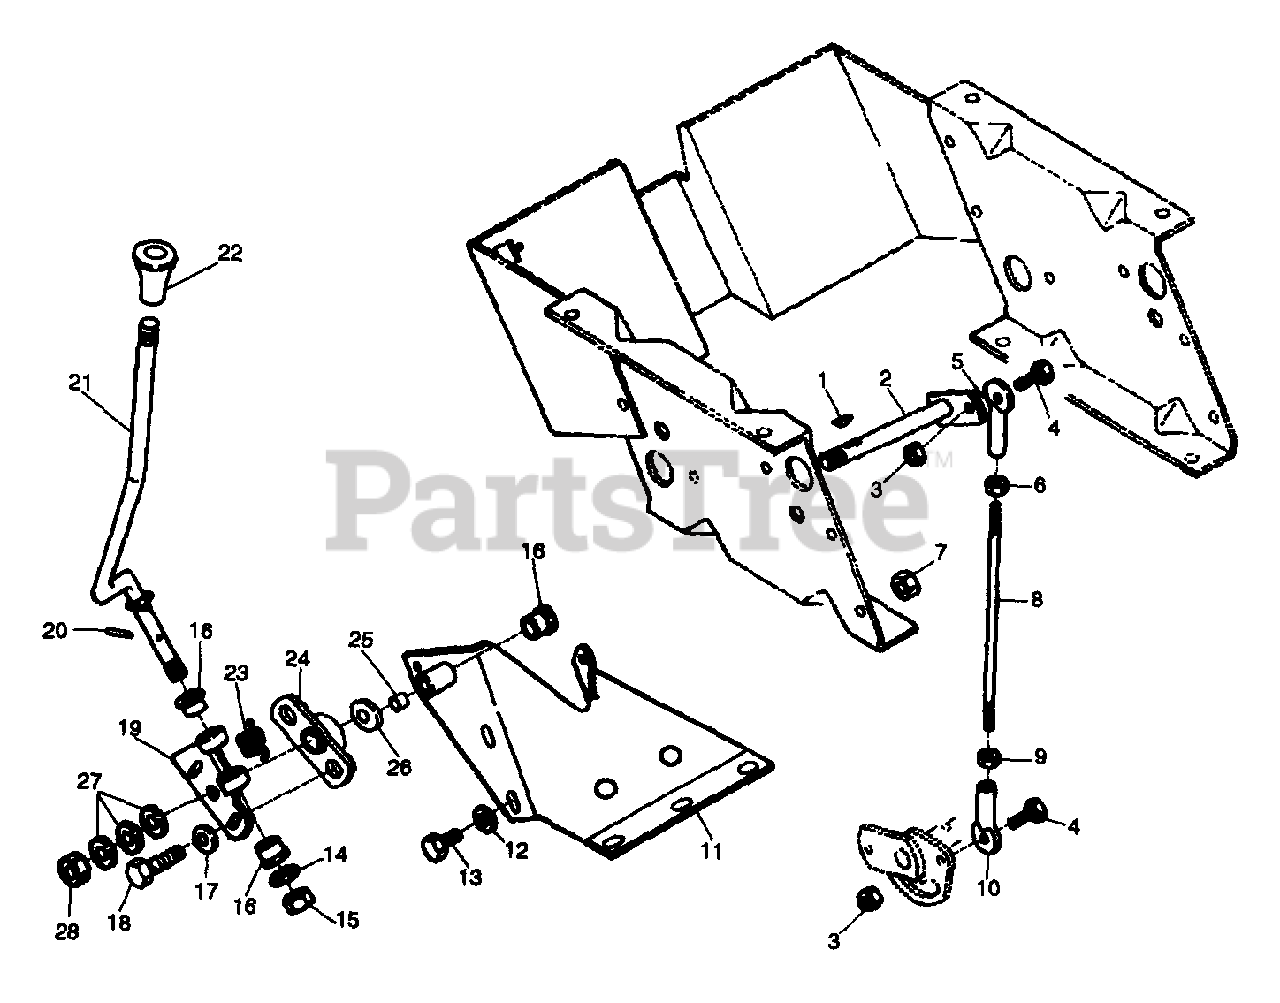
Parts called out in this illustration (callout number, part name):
1	KEY-WDRF .125X.500X.203 SAE 3
3	NUT-LK-CTR .250-20 PL
4	BLT-HEX .25-20X1.00 GR2
5	ROD END, 1/4 RH
6	NUT-HEX .250-28 YWZC
7	NUT-LK .312-18 GR A PL
8	SHIFT ROD
9	NUT-LH .250-28 GR2 PL
10	ROD END, 1/4 LH
12	WSHR-FL-STL.312X.734X.065PL
13	BLT-HEX .31-18X.63 PL GR 2
14	WSHR-FL-STL .520X.827X.062 YZ
15	NUT-LK-CTR .50-20 PL
16	BSHG-FLG .500X.625X.625X.875
17	WSHR-FL-STL .382X.812X.062
18	BLT-HEX .38-16X1.00 PL GR5
19	OUTER ARM
20	PIN-ROLL .125X1.00
21	SHIFT LEVER
23	SG_TORS .08X.56X.65
25	BSHG-SLV .500X.625X.500
26	FRICTION WASHER
27	SPRING WASHER
28	NUT-LK-CTR .50-20 PL
